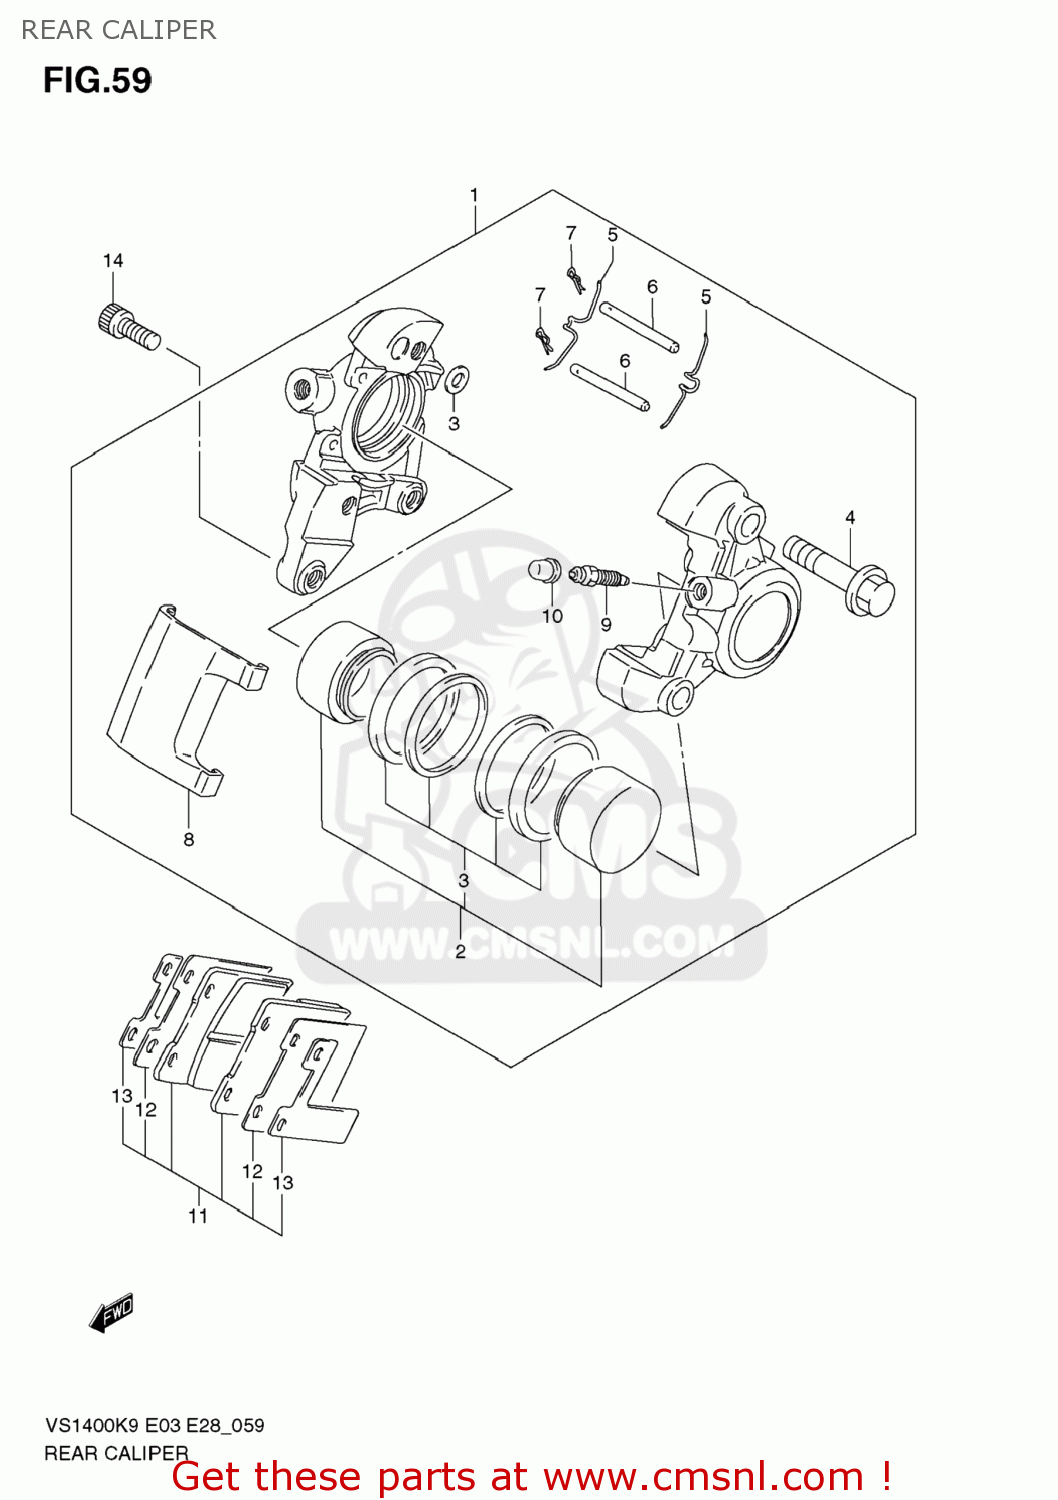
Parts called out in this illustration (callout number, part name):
1	CALIPER ASSY,RR
2	PISTON SET
3	SEAL SET,PISTON
4	BOLT,HOUSING
5	SPRING
6	PIN,PAD
7	CLIP,PAD PIN
8	COVER
9	BLEEDER
10	CAP,BLEEDER PLUG
11	PAD & SHIM SET (NAS)
12	SHIM,PAD
13	SHIM
14	BOLT
